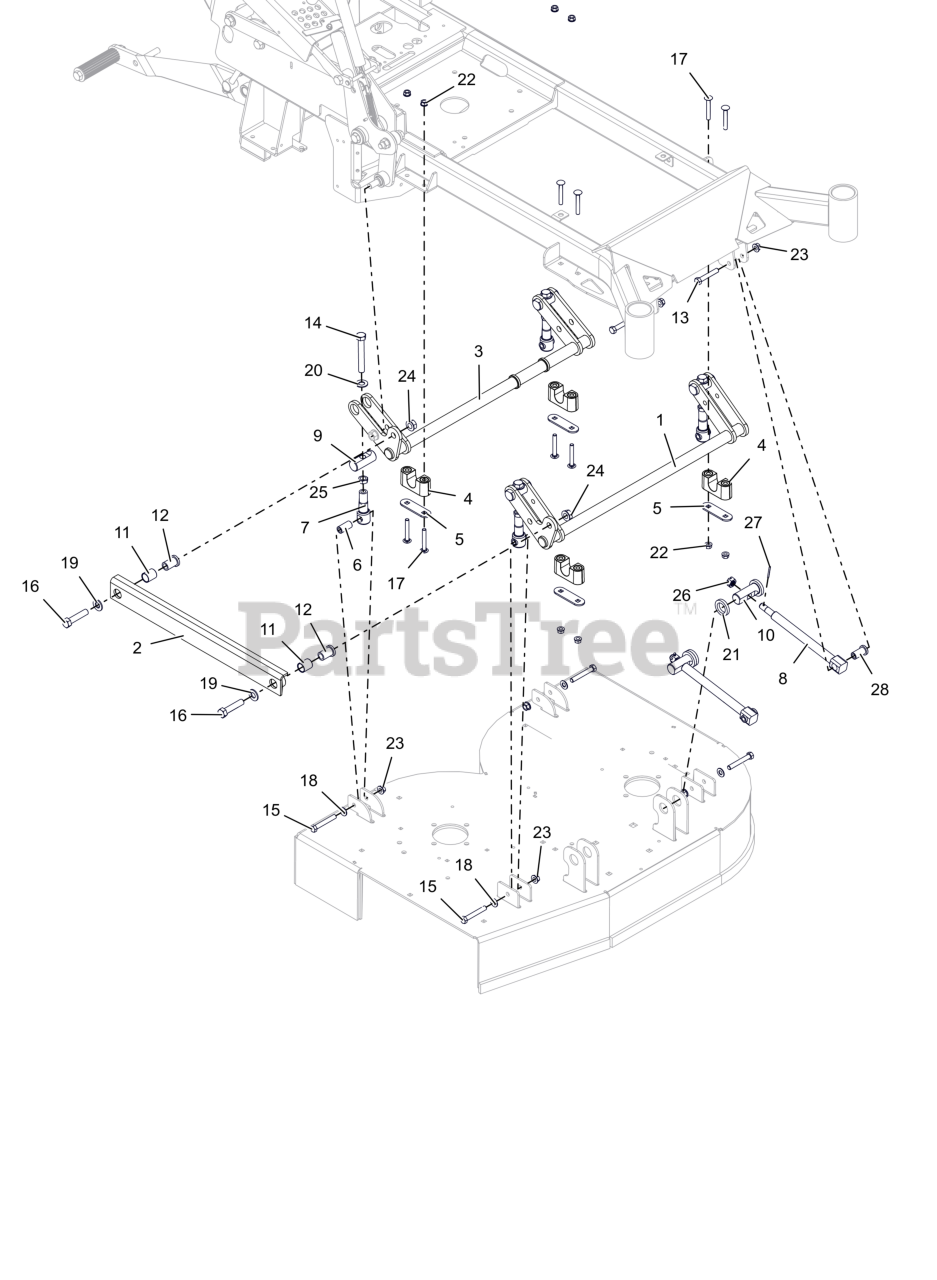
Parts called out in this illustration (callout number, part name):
1	WLDMT, 36" PROSTANCE DECK LIFT (BLACK)
2	WLDMT, DECK LIFT LINK (BLACK)
3	WLDMT, 36" PROSTANCE DECK LIFT (BLACK)
4	ASM-BUSHING, DECK LIFT
5	PLATE, BEARING SUPPORT
6	SPACER, DECK LEVELING
7	LINK, DECK LIFT FORMED
8	DRAG,LINK-HD
9	PIN, DECK LIFT
10	PIN, DECK LIFT
11	BRG- .750 X .875 X 1.000
12	BSHG-FLG .515X.746X1.290X1.000
13	BLT,HEX .38-16X2.25 G5 ZCC
14	BLT, HEX .50-13X3.50F G5 ZCC
15	BLT, HEX .38-16X2.50 G8 ZCC
16	BLT, HEX .50-13X2.25 G5 ZCC
17	BLT, RHSSN.31-18X2.25 G5 ZCC
18	WSHR,FLT .406X.812X.065 ZCC
19	WSHR,FLT .531X1.062X.095 ZCC
20	WSHR, FLT .557X1.040X.102 ZCC
21	WSHR-FL-STL 1.0X1.50X.25
22	NUT,LK-CTR-FLG .31-18 GF ZCC
23	NUT-LK-CTR-FLG .375-16 GF ZCC
24	NUT-LK-CTR-FLG .500-13 GG ZCC
25	NUT-JAM .500-13 G2 ZCC
26	NUT-SL .50-13
27	PIN,CTR.12X1.25EXTPRSQCT ZC120
28	SPCR, DRAG LINK
